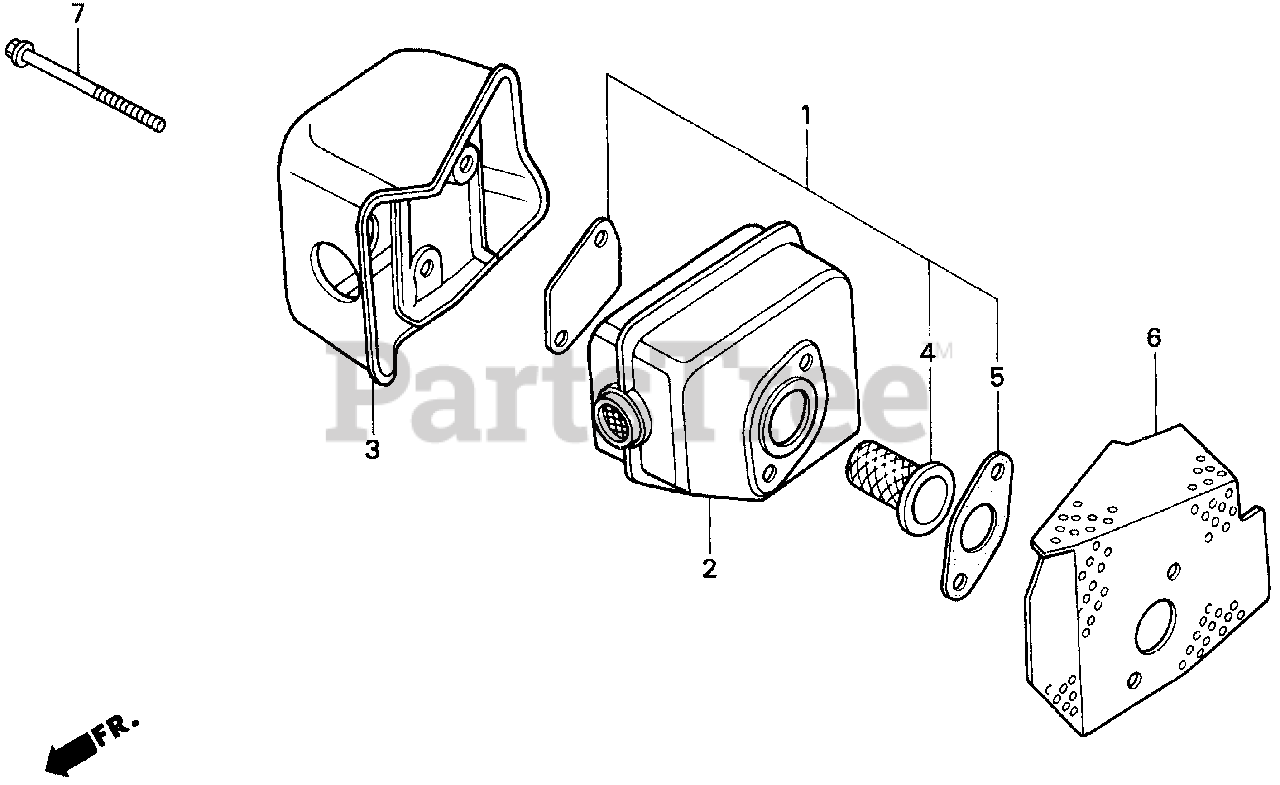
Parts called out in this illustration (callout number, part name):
1	ARRESTER KIT, SPARK
2	MUFFLER
3	PROTECTOR, MUFFLER
4	ARRESTER KIT, SPARK
5	GASKET, MUFFLER
6	GASKET, MUFFLER
7	BOLT, FLANGE (6X85)
